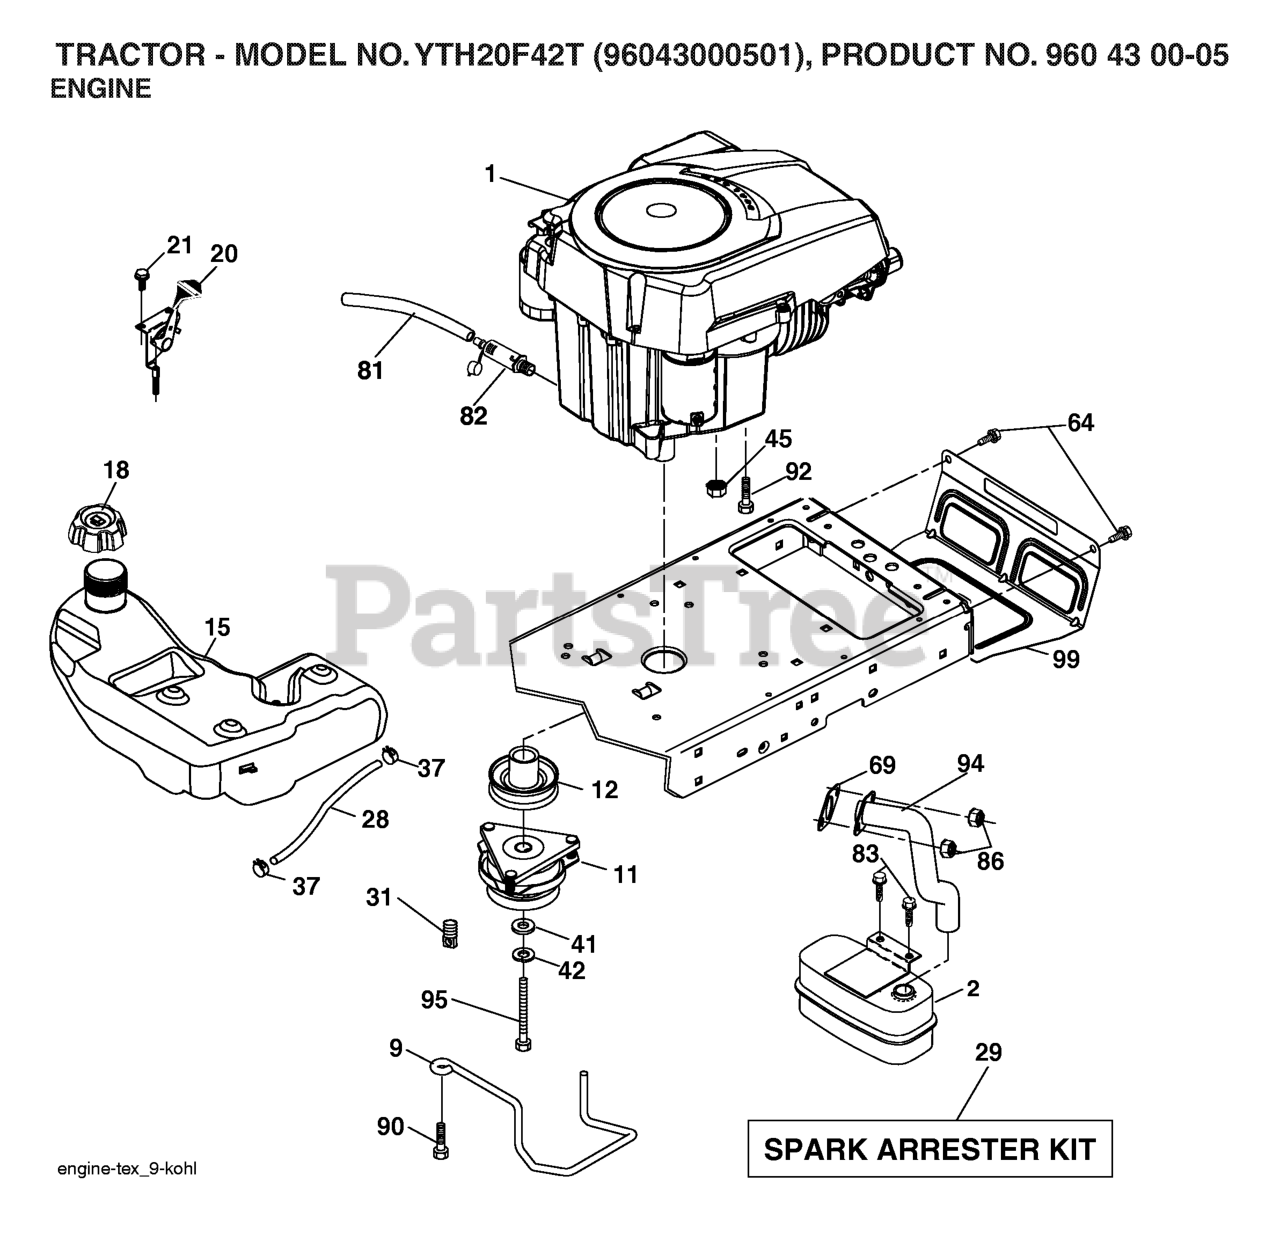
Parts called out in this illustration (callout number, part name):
2	MUFFLER.SINGLE.CYL.KOHL/B&S
9	KEEPER.BELT.ENGINE.4.2
11	RB.CLUTCH.OGURA.4.4.PD
12	PULLEY.ENGINE.TUFFTORQ
15	TANK.FUEL.4GAL
18	CAP.FUEL.TANK.3"GREY
20	CONTROL.TH/CK.COBRA.KO
21	SCREW
29	KIT.SPARK ARRESTOR 794945 B&S
31	DECAL BTRY SYMBOLS
37	HOSE CLAMP
42	LOCKWASHER
45	NUT
64	SCREW, 3/8-16X3/4
69	GASKET.EXHAUST.KOHLER
81	TUBE, DRAIN OIL ASM.
82	PLUG DRAIN OIL EASY
83	BOLT.5/16-18UNCX3/4 W/SEMS.BLK
86	NUT.HEX.FLANGE.TOPLOCK
90	SCREW 3/8-16X1
92	SCREW 3/8-16X1
94	RP.TUBE.EXHAUST.KOHL.COURAGE
95	BOLT HEX 7/16-20X4-1/4"
99	SHIELD.BROWNING/DEBRIS
